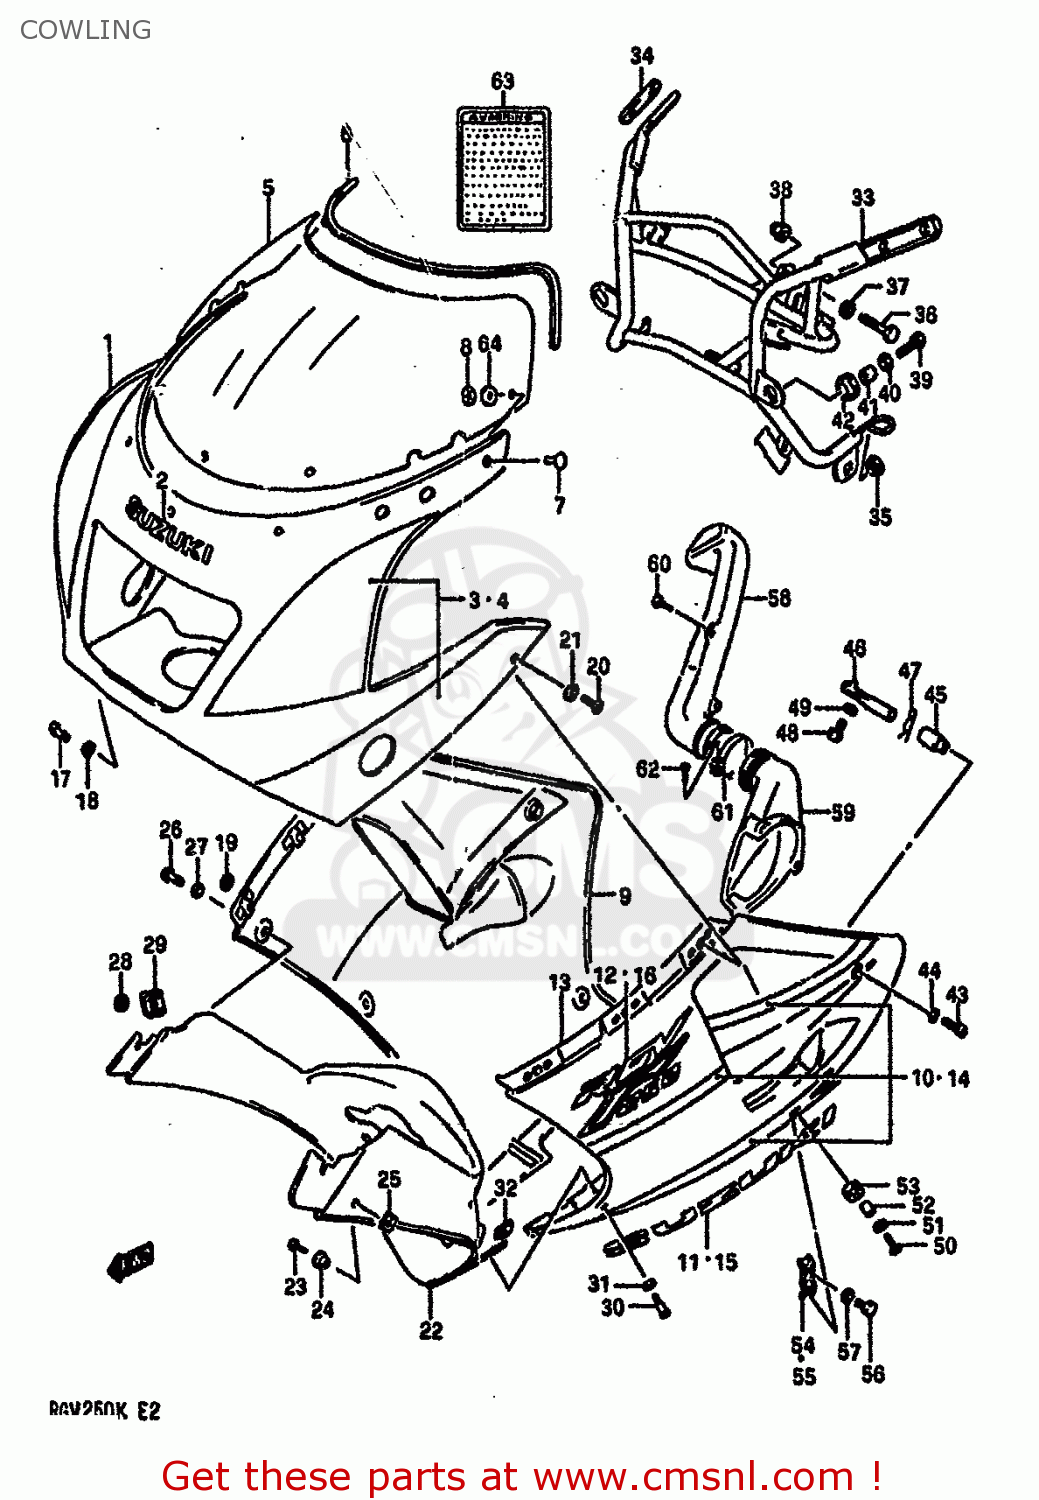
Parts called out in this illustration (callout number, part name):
1	COWLING ASSY (WHITE)
2	EMBLEM
3	TAPE SET,RH
4	TAPE SET,LH
5	WINDSCREEN
6	MOULDING
7	PIN,WINDSCREEN
8	NUT
9	COWLING ASSY,UNDER RH
10	TAPE SET,RH
11	EMBLEM
12	EMBLEM,UNDER
13	COWLING ASSY,UNDER LH
14	TAPE SET,LH
15	EMBLEM
16	EMBLEM,UNDER
17	STUD
18	WASHER(7X13X0.6)
19	RETAINER
20	SCREW(5X16)
21	WASHER(7X13X0.6)
22	COWLING,UNDER CENTER (WHITE)
23	SCREW
24	WASHER(5.2X14X1.5)
25	NUT
26	STUD
27	WASHER(7X13X0.6)
28	RETAINER
29	RECEPTACLE
30	SCREW(5X16)
31	WASHER(7X13X0.6)
32	NUT,HEADLAMP HOUSING,UPPER
33	BRACE,COWLING
34	CUSHION,RR VIEW MIRRORR
35	CAP(OD:17)
36	BOLT
37	WASHER,LOCK,8.
38	NUT ,8MM
39	BOLT
40	WASHER
41	SPACER (6.1X9X10)
42	CUSHION
43	SCREW(6X18)
44	WASHER
45	PLUG,UNDER COWL FTG,CTR
46	PIPE,UNDER COWL FTG CTR
47	PIN,UNDER COWLING FITTING PIPE
48	BOLT 6X16
49	WASHER,LOCK
50	SCREW(6X18)
51	WASHER(6.5X18X1)
52	SPACER (6.1X9X10)
53	CUSHION
54	BRACKET,UNDER LOWER RH
55	BRACKET,UNDER LOWER LH
56	BOLT
57	WASHER,LOCK
58	BODY,AIR DUCT COWLING NO.1
59	BODY,AIR DUCT COWLING NO.2
60	SCREW, FRONT & REAR
61	CLAMP
62	SCREW 4X25
63	LABEL (WARNING SCREEN)
64	CUSHION
